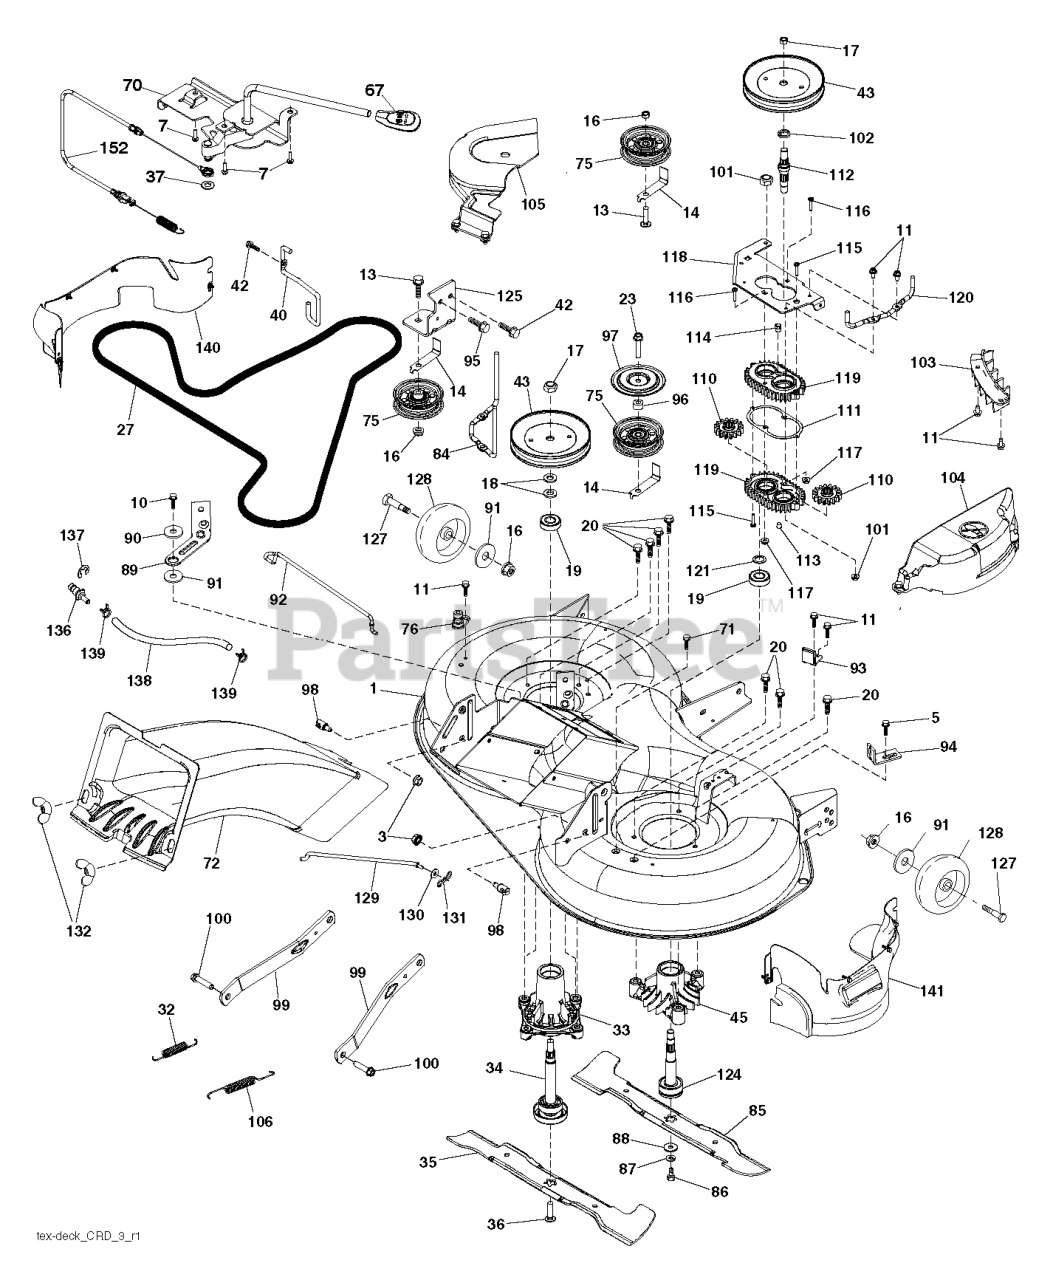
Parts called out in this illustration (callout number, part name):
1	DECK.WELDMENT.97.TEX.498
3	NUT LOCK HEX FLANGE 5/16-18
5	BOLT.5/16HEX.WHS.HD
7	SCREW.#10 X 0.750.BOS
10	SCREW 3/8-16X1
11	SCREW.1/4-20X5/8
13	BOLT.3/8-16X1.50
14	KEEPER, BELT IDLER
16	NUT LOCK FLG 3/8-16 UNC
17	NUT.FLANGE.LOCK.TOP
18	WASHER.SPACER.MANDREL
20	SCREW, WASHER HEAD
23	SCREW LT
27	BELT V-BELT DRIVE
32	SPRING RETURN
33	RP.HOUSING.MANDREL.4PT.
34	SHAFT.ASM.MDRL.N/GREASE.38
35	BLADE.3N1.LH.CRD.97
36	BOLT.WASHER.ASM.7/16-2
37	WASHER
40	KEEPER BELT ENGINE LH
42	SCREW
43	PULLEY.MANDREL.5.438.PD
45	HOUSING.MANDREL.44/46" VENT
67	HANDLE.CLUTCH.CABLE.LT
70	CLUTCH.ASM.MANUAL.LT.PRED
71	SCREW 3/8-16X1/2
75	FLAT IDLER PULLEY
76	1/2" BARB.DECK.WASHOUT.PORT
80	PALNUT 1/4
84	KEEPER.BELT.MANDREL.PULLEY
85	BLADE.3N1.RH.CRD.97
86	BOLT.3/8-24X1.25GR8. LHTHRD
87	LOCKWASHER
88	WASHER.BLADE
89	ARM.BRAKE.97.LH
90	SPACER.RETAINER
91	WASHER
92	ROD ROD BRAKE
93	ARM.BRAKE.97.RH
94	BRKT.CLUTCH.CABLE
95	SCREW, 3/8-16X3/4
96	SPACER
97	PROTECTOR
98	STUD.FASTNER.W/ANTI-ROTATE
99	ARM.SUSPENSION.MOWER.R
100	BOLT.SHOULDER
101	NUT.CROWNLOCK.9/16 -18.UNC
102	SPACER BEARING
103	GUARD GUARD FRONT VENT
104	97.CRD.RH.MANDREL.COVER
105	MANDREL MANDREL COVER LH
106	SPRING.BRAKE.RETURN.38"
110	CRD.SPUR.GEAR
111	GASKET GASKET GEARCASE
113	PLUG PLUG OIL
114	VALVE VALVE RELIEF
115	SCREW
116	BOLT.CARIGE.SS.1/4-20X1.75GR5
117	NUT T
118	ARM ARM CLUTCHING
119	GEARCASE GEARCASE SUBASM
120	BRACKET KEEPER BELT RH
121	WASHER WASHER
124	MANDREL SHAFT NON/GREASE
125	BRACKET BRACKET IDLER CHASSES
127	BOLT.SHOULDER.3/8-16X3-5/8.
128	RP WHEEL. GUAGE RALLY
129	ROD.ANTI.SWAY.48/54"K4
130	WASHER
131	PIN.COTTER.5/16.BOW TI
132	KNOB.HANDLE.3/8.TRI-POINT.BLAC
136	PLUG WASHOUT PORT HOOKUP
138	HOSE.3/8ID.BULK.12"
139	HOSE.3/8.CLAMP (2 2)
152	CABLE CABLE CLUTCH MANUAL W/S
